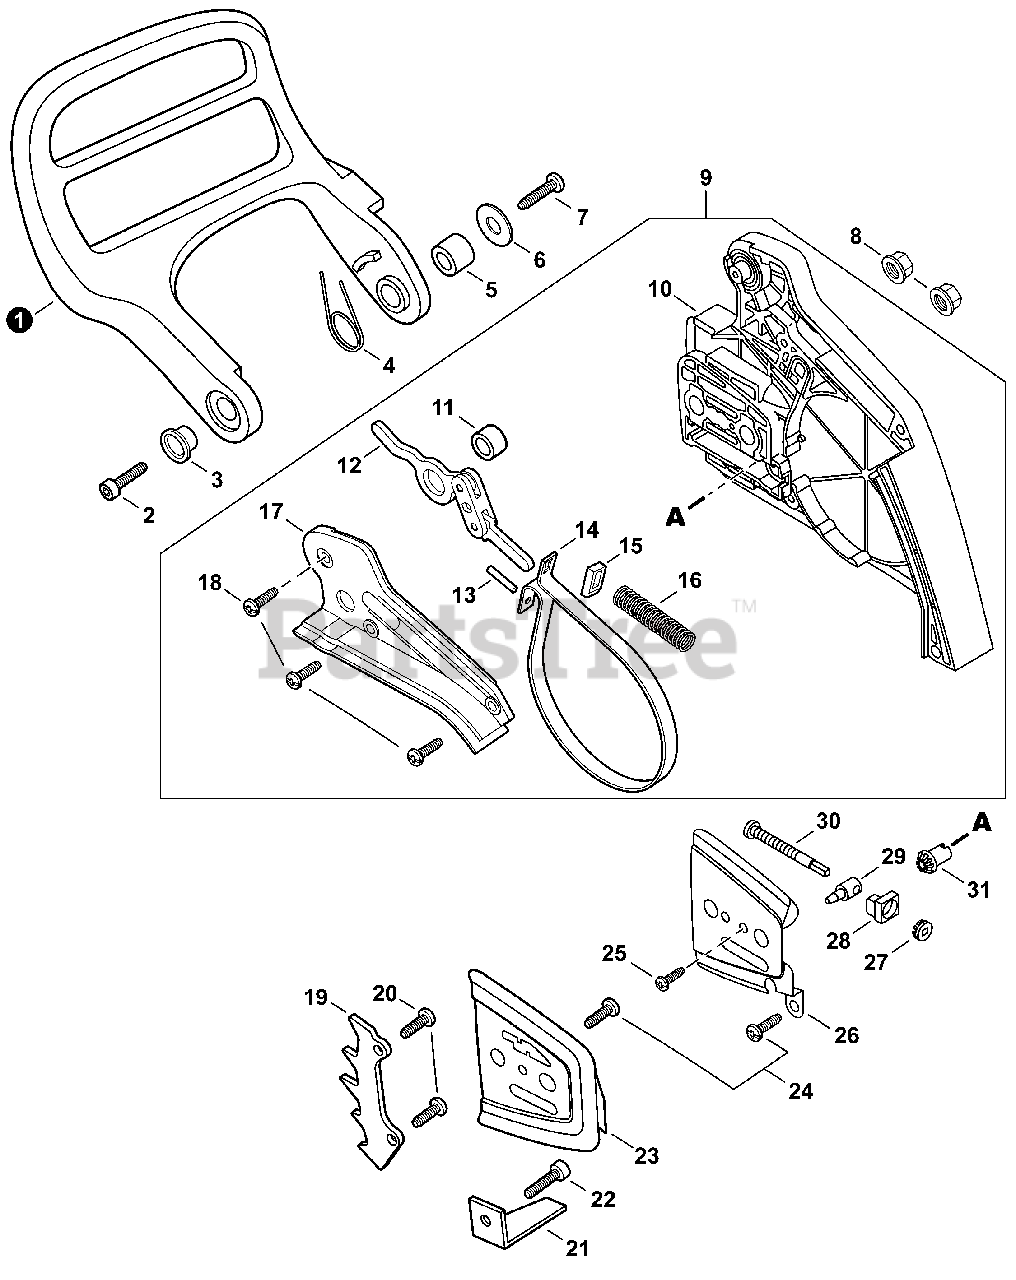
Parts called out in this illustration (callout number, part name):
1	LEVER, BRAKE
2	SCREW TAPPING 5×16
3	COLLAR 10
4	SPRING, TORSION
5	SPACER 8×12×9
6	WASHER 4.2×16.5×1
8	NUT, FLANGE M8×1.25
9	BRAKE ASSY, CHAIN
10	GUARD, SPROCKET
11	SPACER 8×12×9
12	CONNECTOR, BRAKE
13	PIN, SPRING 3×9.8
14	BAND, BRAKE
16	SPRING, COMPRESSION
17	COVER, BRAKE
18	SCREW 4×12
19	SPIKE, BUMPER
20	SCREW TAPPING 5×20
21	CHAIN CATCHER
22	SCREW TAPPING 5×16
23	PLATE, GUIDE - INNER
24	SCREW 4×12
25	SCREW 3×6
26	PLATE, GUIDE - OUTER
27	GEAR, BEVEL
28	COLLAR 8
29	TENSIONER, CHAIN
30	SCREW, CHAIN TENSION
31	GEAR, BEVEL
